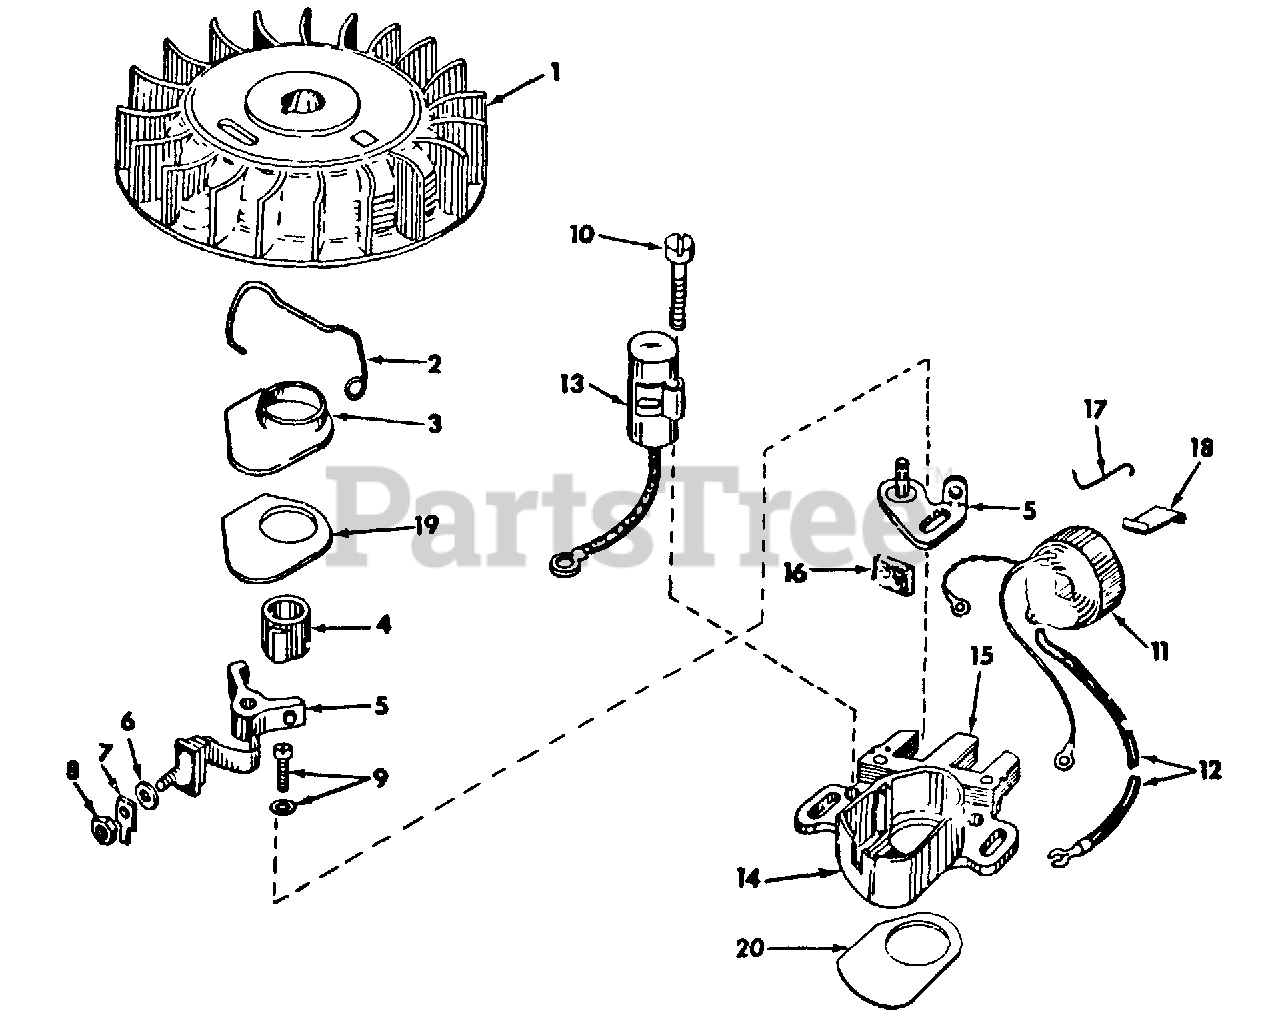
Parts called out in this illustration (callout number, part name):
1	FLYWHEEL
2	SPRING, BREAKER BOX
3	COVER, BREAKER DUST
4	CAM, BREAKER
5	CONTACT ASSY, BREAKER
6	WASHER, NO 8 C-Z HV. LOCK
7	TAB, GROUND TERMINAL
8	NUT, 8-32 C-Z HEX. MACH SCREW
9	SCREW AND WASHER, BREAKER
10	SCREW, 8-32 X 13/16 C-Z TYPE F SLT-HEX.
11	COIL ASSY
12	WIRE, LEAD
13	CONDENSER
14	CORE AND PLATE
15	STATOR ASSY
16	FELT, CAM WIPER
17	CLIP, COIL LOCKING
18	CLIP, COIL WEDGE SPRING
19	GASKET, DUST COVER
20	GASKET, DUST SHIELD
